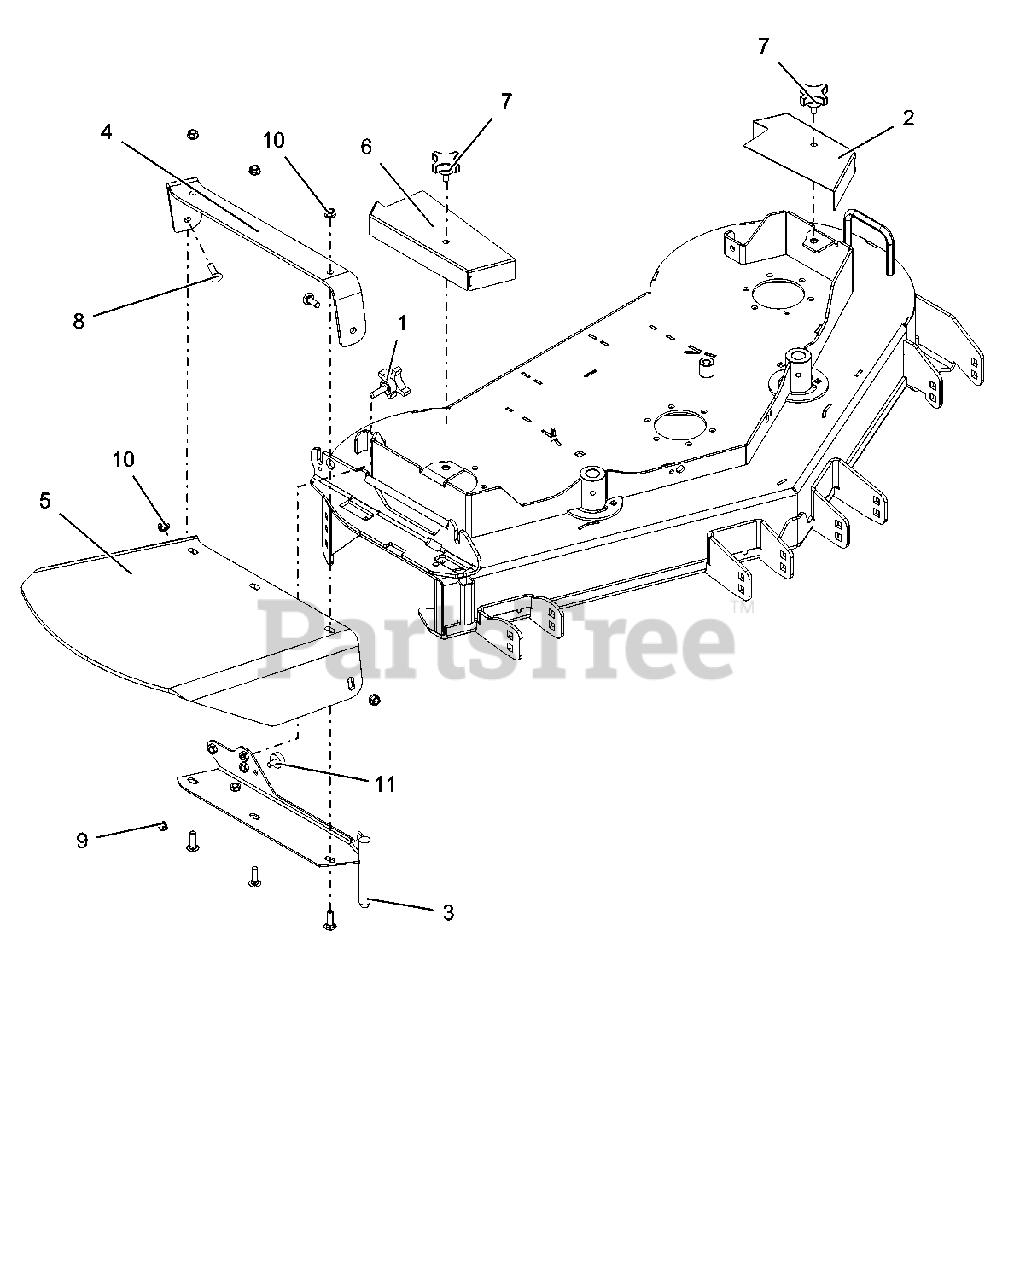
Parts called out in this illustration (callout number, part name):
1	KNOB, 3/8 X 1.25 - 4 PRONG
2	SHIELD, LH SPINDLE 48 FLWLK-RED
3	WLDT. DISCHARGE-RED
4	STRAP, WALK RUBBER DISCHARGE-RED
5	SHIELD, WALK RUBBER DISCHARGE
6	SHIELD, RH SPINDLE 48 FLWLK G2-RED
7	KNOB, 3/8-16 x .75
8	BLT-RDHDSQNK .38-16X1.25 G5 YWZC
9	@NUT-SPNLK-FLG .312-18 YWZC
10	@NUT-SPNLK-FLG .375-16 YWZC
11	BUMPER, RUBBER
